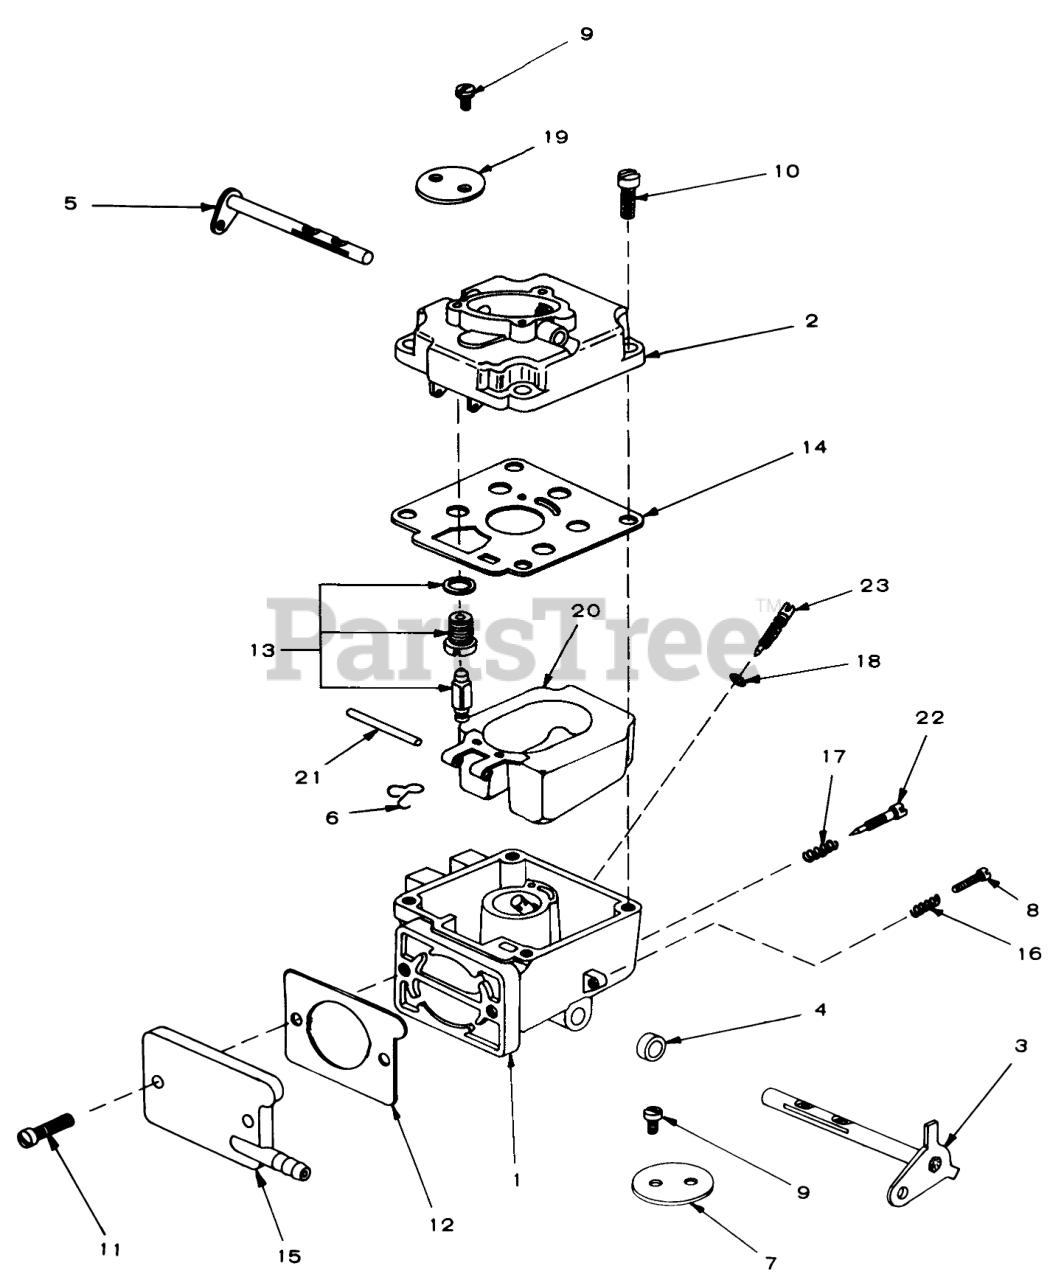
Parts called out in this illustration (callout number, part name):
1	Lower Body Assy
2	Sleeve Assy
3	Shaft-Throttle
4	Packing Shaft
5	SHAFT-CHOKE
6	CLIP-FLOAT VALVE
7	Throttle Fly
8	Screw-Throttle Stop
9	Screw-Fly Mounting
10	SCREW-BOWL COVER MTG
11	Screw-Inlet Plate
12	Gasket-Plate
13	Float Valve Assy
14	GASKET
15	Carburetor Inlet Plate
16	Spring-Throttle Stop
17	Spring-Idle Needle
18	GASKET-O RING
19	Choke Fly
20	Float & Lever Assy
21	Shaft,Float Lever
22	Idle Needle
23	High Speed Needle
23	Gasket Set (Includes Parts Marked )
23	Repair Kit (Includes Parts Marked )
